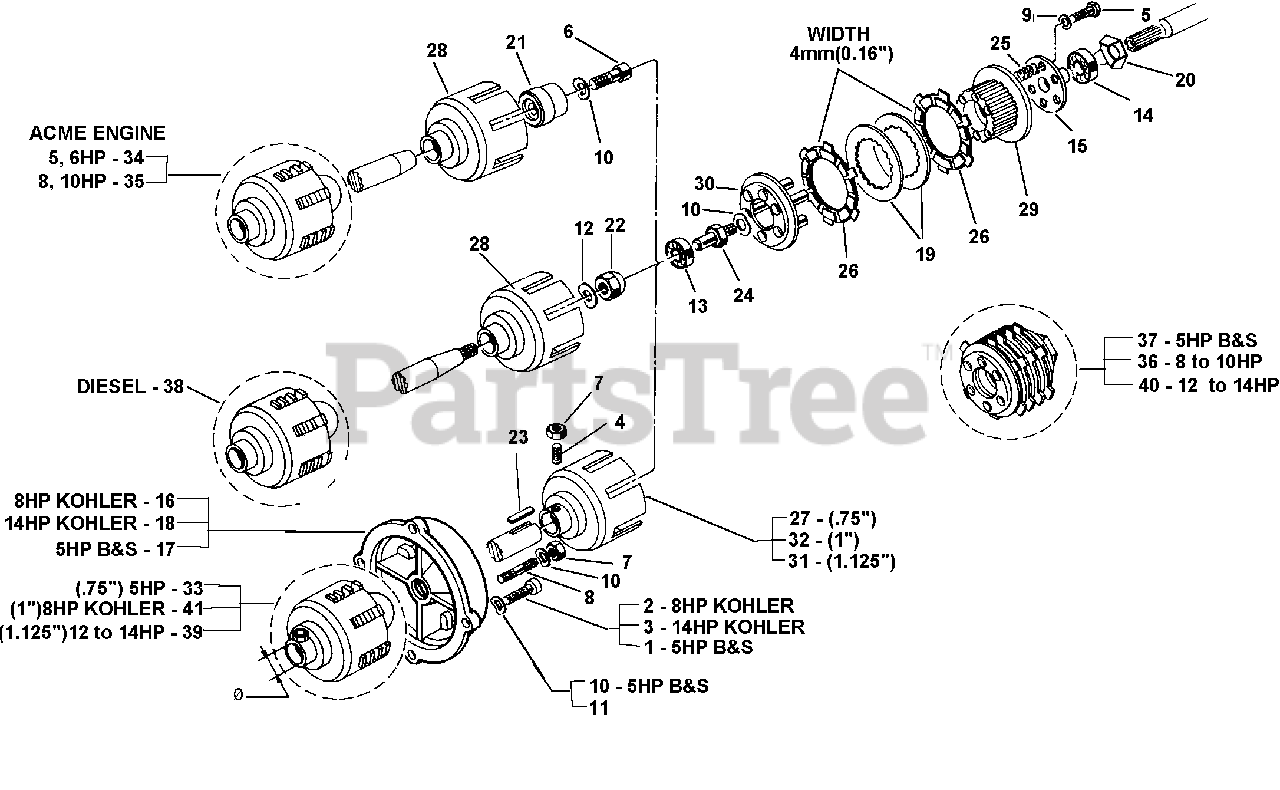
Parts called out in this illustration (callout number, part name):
1	SCREW 5/16 X 7/8
2	SCREW 3/8 X 1
4	SCREW M8 X 14
6	SCREW M8 X 25
8	STUD M8 X 40 X 14 X 14
9	SUPER WASHER
10	WASHER, LOCK 8.4
11	WASHER, LOCK 10.5
12	WASHER, LOCK 17
14	BEARING 17 X 40 X 12
15	CLUTCH FLANGE
16	FLANGE FOR KOHLER ENGINE 8HP
17	FLANGE FOR 5HP B&S
18	FLANGE FOR KOHLER ENGINE 14HP
19	INSIDE CLUTCH DISC
20	BEARING PLATE
21	BEARING HOLDER BUSHING
22	SPECIAL NUT
24	SCREW 9 X 1
25	DISC CLUTCH SPRING
26	OUTSIDE DISC
27	CLUTCH BELL
28	CLUTCH BELL
30	CLUTCH BOTTOM
31	KOHLER CLUTCH BELL
32	CLUTCH BELL
33	DISC CLUTCH ASSEMBLY
34	DISC CLUTCH ASSEMBLY
35	DISC CLUTCH ASSEMBLY
36	DISC ASSEMBLY
37	DISC ASSEMBLY
38	DISC CLUTCH ASSEMBLY
39	DISC CLUTCH ASSEMBLY
40	DISC ASSEMBLY
41	DISC CLUTCH ASSEMBLY
